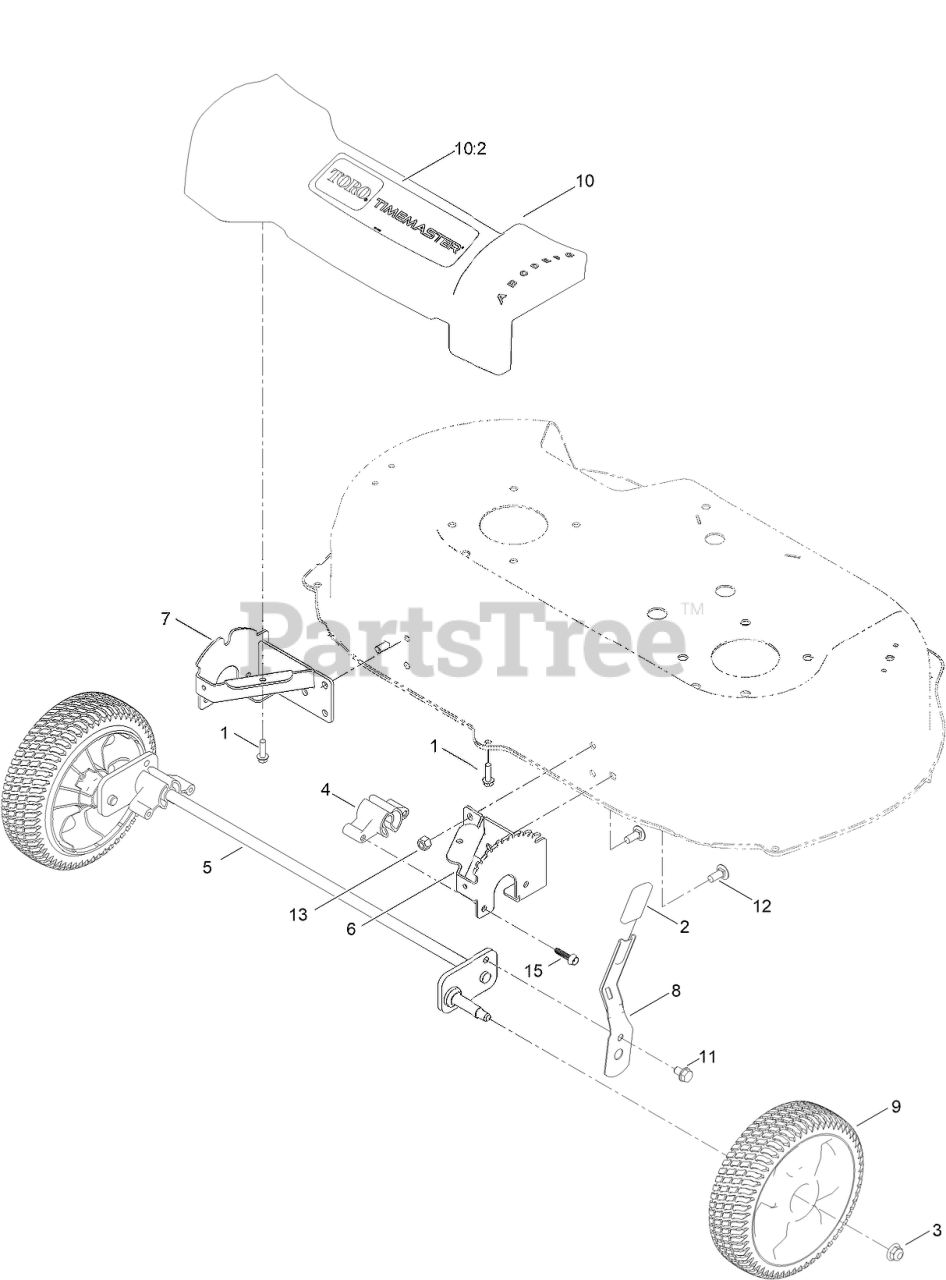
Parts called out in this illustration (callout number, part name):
1	SCREW-HWH
2	GRIP-LEVER
3	NUT-HF, NI
4	BUSHING-PIVOT, FRONT
5	FRONT AXLE ASM
6	PLATE-HOC, LH
7	PLATE-HOC, RH
8	ARM-SPRING
9	8 INCH WHEEL ASM
10	FRONT COVER ASM
10:2	DECAL-COVER, FRONT
11	SCREW-HWH
12	SCREW-CARR
13	NUT-LOCK, NI
15	SCREW-FLANGE, PLASTIC
